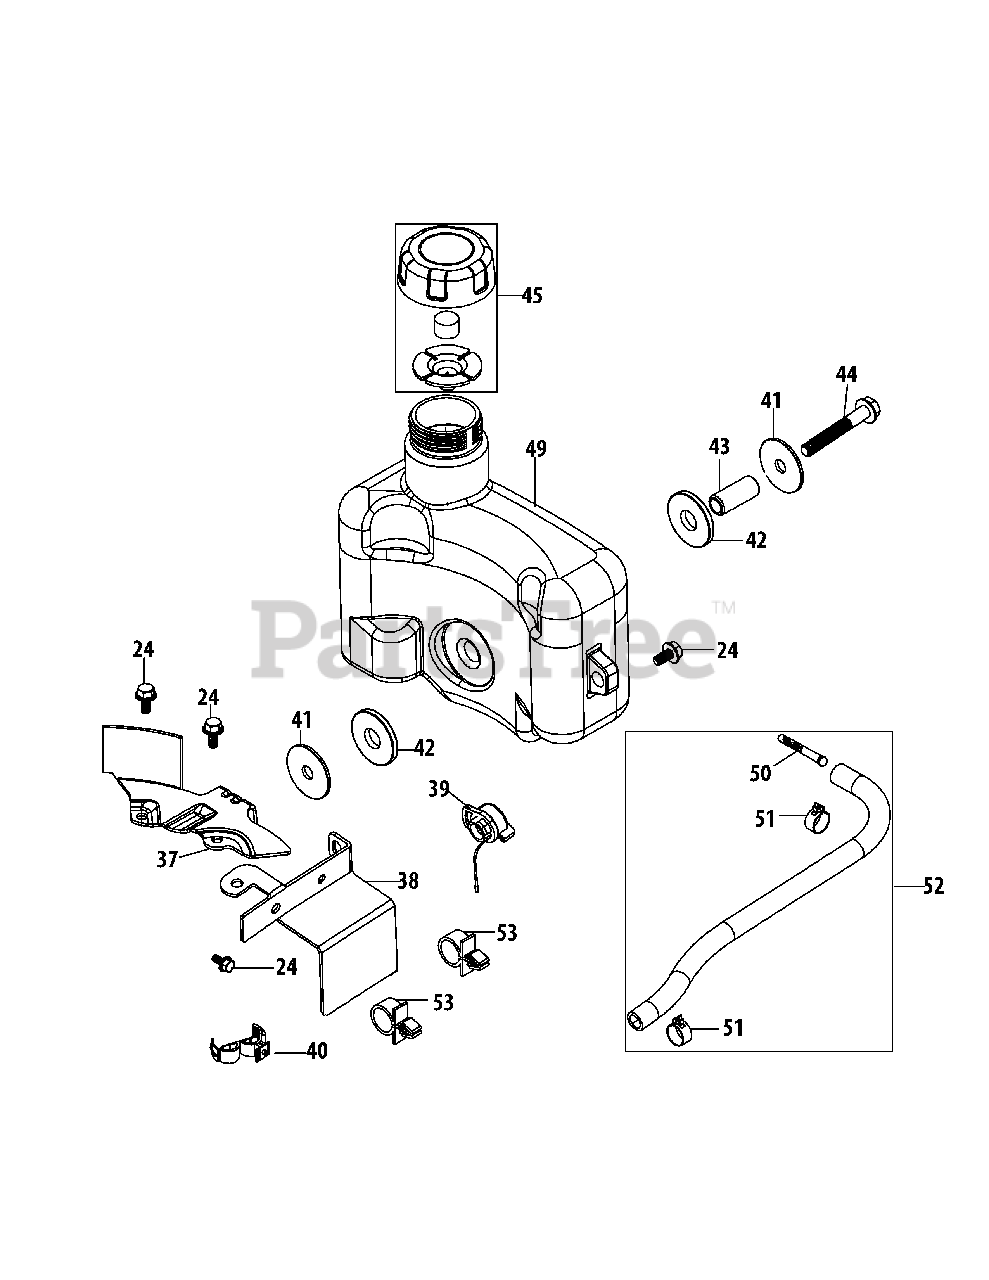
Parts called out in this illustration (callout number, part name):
24	Bolt M6X14 Multi-Purpose
37	Fuel Tank Bottom Bracket
38	Fuel Tank / Console Bracket
39	Ignition Switch
40	Wire Clamp
41	Fuel Tank Washer
42	Rubber Bushing
43	Fuel Tank Bushing
44	Bolt M8X50 Fuel Tank
45	Fuel Cap Assembly
49	Fuel Tank Assembly
50	Fuel Filter
51	Fuel Hose Clamp
52	Fuel Line Kit
53	Plastic Support Clamp
